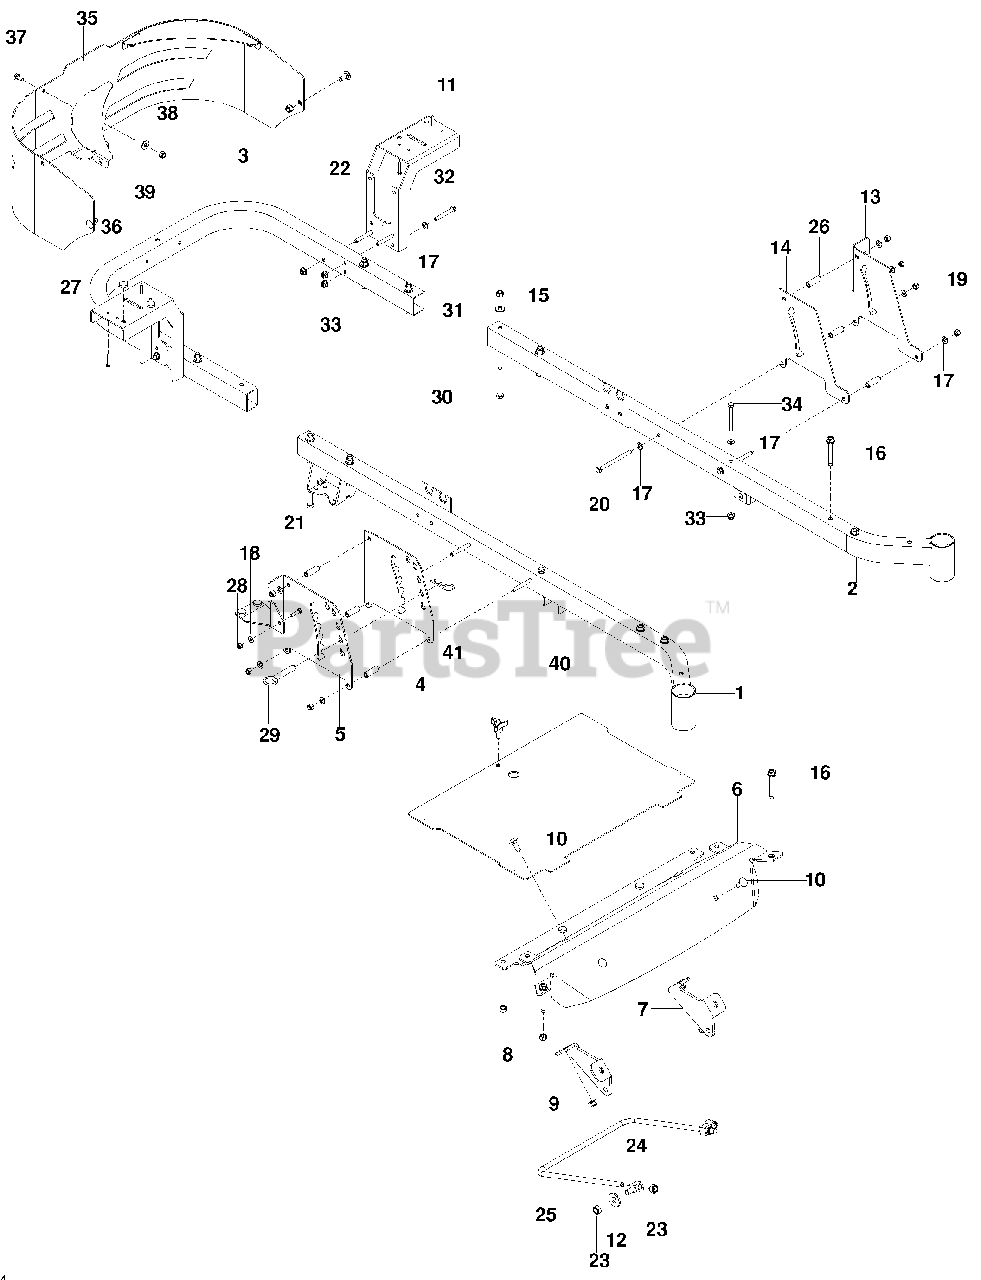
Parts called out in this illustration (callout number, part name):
1	FRAME, FRONT RT ORG
2	FRAME, FRONT LT ORG
3	FRAME, REAR ORG
4	PLATE, OUTER HEIGHT BLK
5	PLATE, INNER HEIGHT BLK
6	FOOT REST ORG
7	MOUNT, STRUT, RT
8	MOUNT, STRUT, LT
9	NUT 3/8-16 HEX FLG NYLOC
10	RHSNB 3/8-16 x 1
11	SUPPORT, FENDER BLK
12	WASHER 1/2 FLAT
13	PLATE, OUTER BRAKE BLK
14	PLATE, BRAKE LATCH BLK
15	NUT 3/8-16 HEX NYLOC
16	BOLT 3/8-16 x 25/8 THD FRM
17	WASHER 5/16 SAE FLAT
18	WASHER 1/4 FLAT SAE
19	NUT 5/16-18 HEX NYLOC
20	HCS 5/16-18 x 4
21	HCS 1/4-20 x 1
22	SCREW 10-12 x 1 1/4 WSH HD
23	NUT 7/16-14 HEX NYLOC
25	LINK, FRONT SUSPENSION
26	SPACER 1/2 OD x 1 1/2
27	GROMMET, BUMPER
28	NUT 1/4-20 HEX NYLOC
30	HCS 3/8-16 x 3
31	WASHER 3/8 SAE FLAT
32	HCS 5/16-18 x 2 1/4
33	NUT 5/16-18 FLANGE NYLOC
34	HCS 5/16-18 x 2 3/4
35	GUARD, WIDE ENGINE ORG
36	SUPPORT, CORNER ORG
37	RHSSNB 1/4-20 x 5/8
38	NUT 1/4-20 HEX NYLOC
39	WASHER 1/4 FLAT
40	FOOT PLATE w/DECALS ORG
